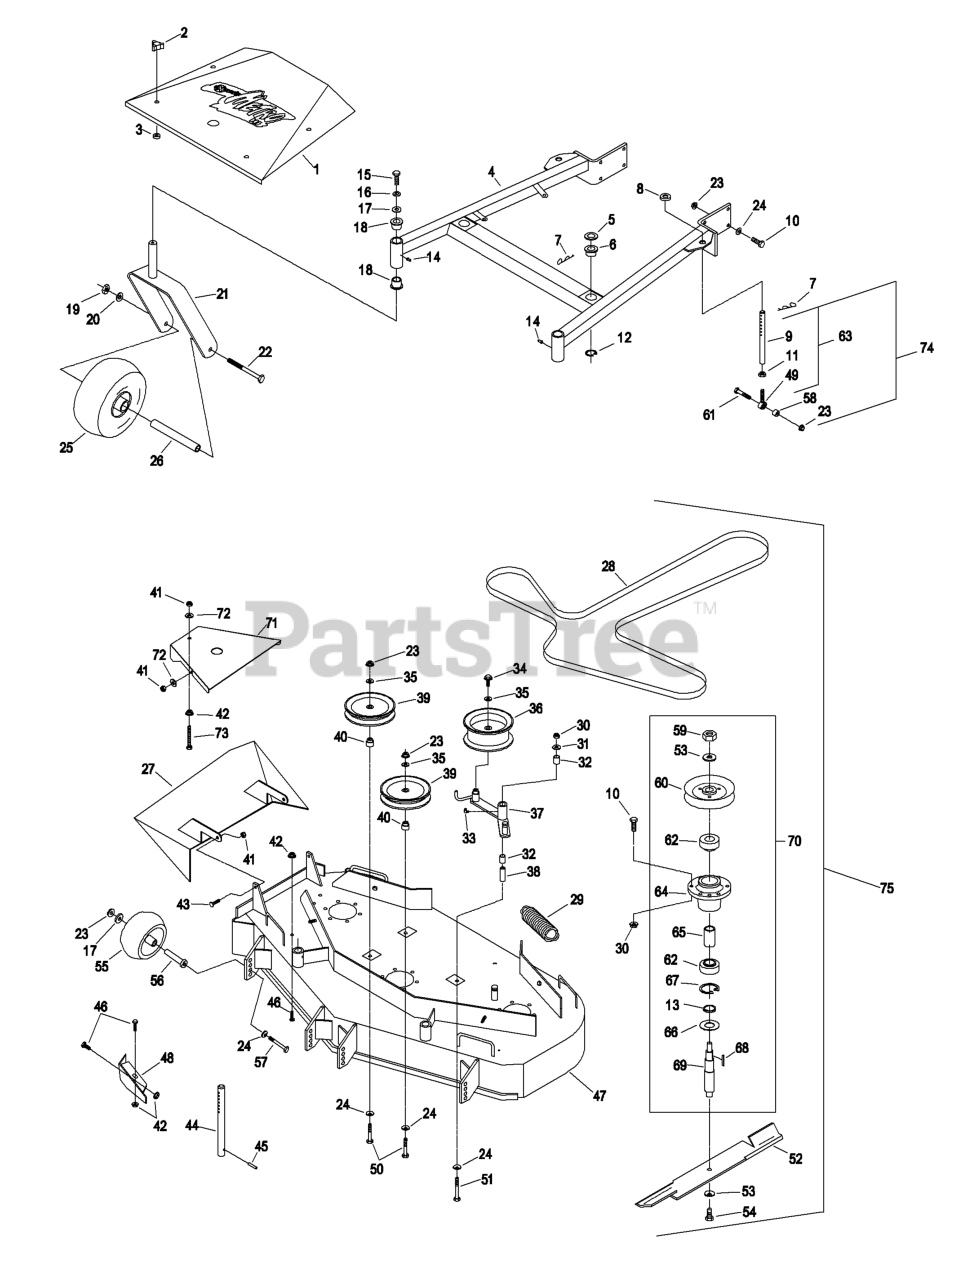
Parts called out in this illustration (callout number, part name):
1	SHIELD W/DECAL,MHP48
2	KNOB-3 PRONG
4	DECK SUPPORT W/BSHGS 48"
5	SPACER-DECK SUPPORT
6	BUSHING-DECK
7	PIN,HAIR COTTER
9	LINK,SUPPORT
10	SCREW-HH
11	NUT-HEX
12	RING-RETAINING
13	SPACER-PULLEY/BEARING
14	FITTING-GREASE
15	SCREW-HH
16	WASHER-LOCK
18	BEARING-FLANGED
19	NUT-HH
20	WASHER-LOCK
22	SCREW-HH
23	NUT-HHF, WHIZ
24	WASHER-BELLEVILLE
28	BELT - V, B
30	NUT-LOCK, NI
31	WASHER-FLAT
32	SLEEVE-BEARING
33	FITTING-GREASE, 90 DEG
34	SCREW-HHF
35	WASHER-FLAT
38	BUSHING-PIVOT, IDLER
39	PULLEY-IDLER
40	BUSHING-IDLER
41	NUT-LOCK, NI
43	SCREW-HH
44	ROD,DECK SUPPORT
46	SCREW-HH
47	ASM,DECK W/DECALS TTHP/MH
49	BALLJOINT
50	SCREW-HH
51	SCREW-HH
53	WASHER-SPRING
54	SCREW-CAP
55	ROLLER-SCALP, ANTI
56	BUSHING-ROLLER
57	SCREW-HH
59	NUT-HEX
60	SHEAVE,W/HUB 5.72
61	SCREW-HH
62	BEARING
65	SPACER-BEARING
66	GUARD-BEARING, BOTTOM
67	RING-SNAP
68	KEY-RECTANGLE
69	SHAFT,SPINDLE
70	HOUSING,CUTTER COMPLETE
72	WASHER-FLAT
73	BOLT,TAP HH
75	Assembly, Cutting Deck
